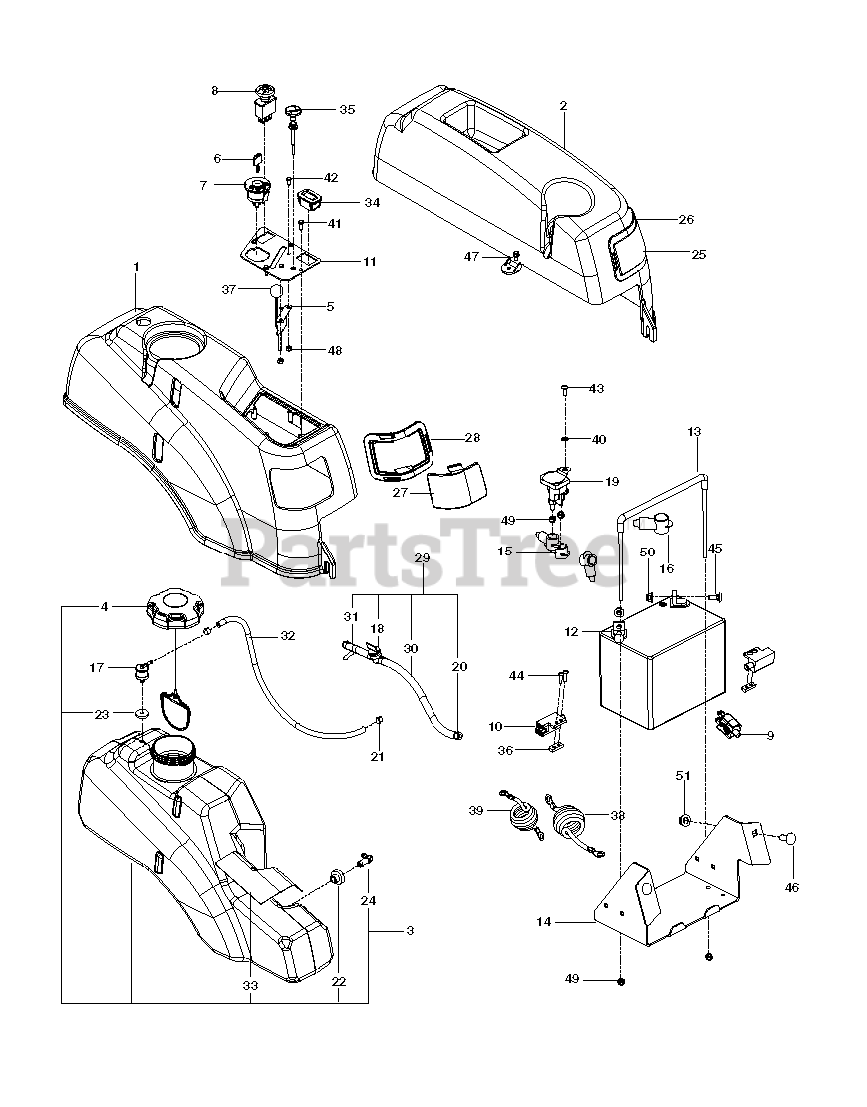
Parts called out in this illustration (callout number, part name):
1	FENDER RT, GRAY
2	FENDER, LT
3	TANK.FUEL.ASSEMBLY.LARGE
4	CAP, FUEL
5	THROTTLE CABLE
6	KEY MLD GEN DELTA
7	RP IGNITION SWITCH
8	RP SWITCH.PTO.8.TERMINAL.RED
9	SWITCH, BRAKE 3P
10	SWITCH INTERLOCKT
11	CONSOLE.PLATE.BLACK
12	BATTERY, 12 V 330 AMP
13	BATTERY TIE DOWN ASSEMBLY
14	BOX, BATTERY, BLACK
15	TERMINAL COVER-SM
17	VALVE.FUEL.CHECK
18	FUEL VALVE
19	SOLENOID.W/BRASS.PLUNGER
20	HOSE CLAMP
21	CLAMP, HOSE
22	RUBBER GROMMET
23	GROMMET, CHECK VALVE
24	STEM, FUEL TANK
25	LENS, COLORED LEFT
26	LEFT HEADLIGHT RIM GREY
27	LENS, COLORED RIGHT
28	RT HEADLIGHT RIM GREY
29	ASSEMBLY, FUEL LINE, KAW
30	GAS LINE 10"
31	FUEL LINE 14"
32	HOSE, VAPOR 3/16 X 48"
33	SHIELD, HEAT
34	RP.GUAGE.SRVCMNDR.HRMTR.
35	CHOKE CABLE
36	TAPPED PLATE
37	KNOB.ROUND.BALL.BLACK
38	CABLE POSITIVE, LONG
39	BATTERY CABLE, NEGATIVE
40	WASHER 1/4 INT TOOTH
41	SCR #10-12X3/4 HEX WAS HD ZD
42	HCS #10-24 X 1/2
43	SCR 1/4-20 X 5/8 BTN SKT HD ZD
44	SCR #10-24 X .75 SKT HD BLK
45	BOLT 5/16C X 3/4" CARRIAGE
46	RHSNB 3/8C X 1
47	BOLT 1/4-20 X 1/2 HWST
48	NUT 10-24 NYLOC
49	NUT.1/4-20.HEX.NYLOC.ZD
50	5/16-18 NYLOC FLANGE NUT
51	NUT 3/8-16 HEX FLG NYLOC ZD
